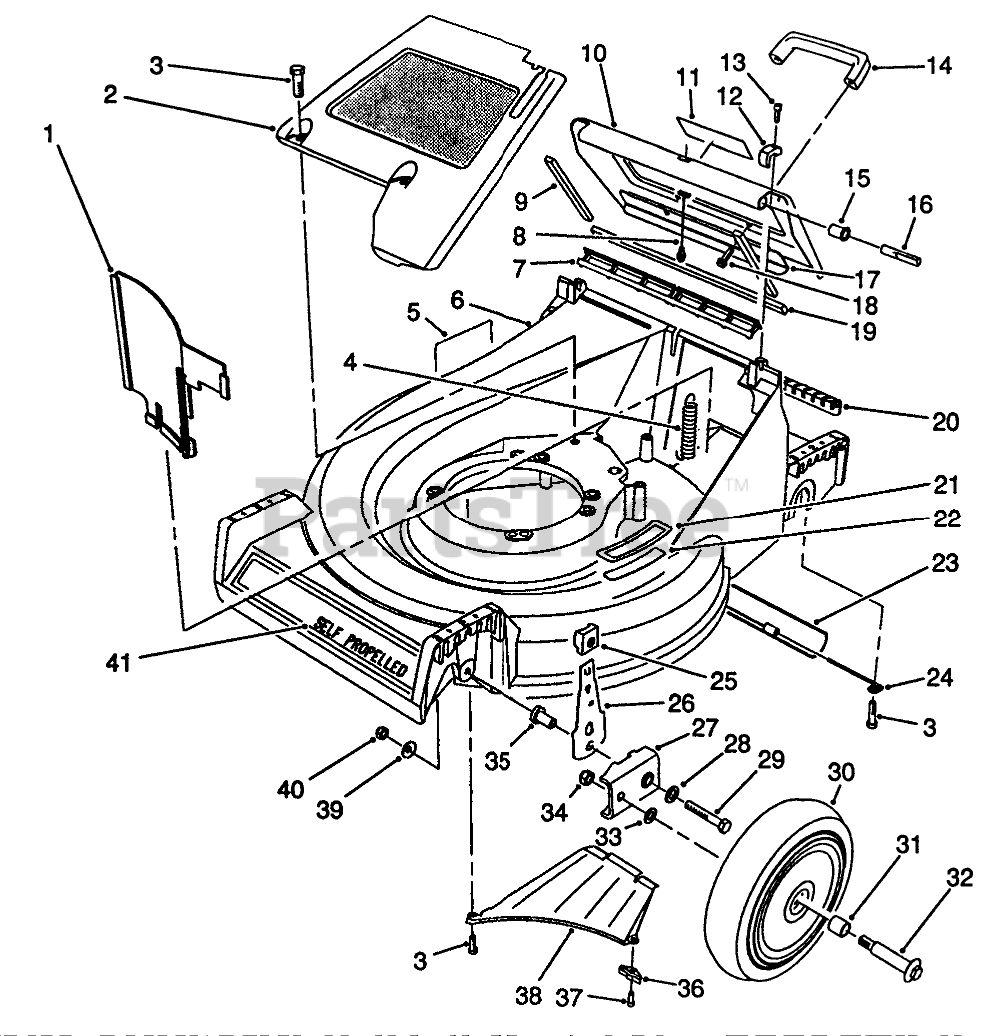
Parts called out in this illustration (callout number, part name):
1	PANEL-VERTICAL
2	PaneI-Screen
3	SCREW-HWHTF
4	EXTENSION-SPRING
5	DECAL-DANGER
6	21" Housing Assembly (Incl. Ref. #5, & 21-22)
7	DOOR SEAL
8	DOOR CABLE
9	DOOR SIDE SEAL
10	Door-Discharge (Incl. Ref. #9, 11, 17 & 19)
11	DECAL - WARNING
12	HINGE CLAMP
13	SCREW-HSH
14	HANDLE-DOOR
15	DOOR BUSHING
16	HINGE PIN
17	DOOR - BRACE
18	SCREW-HWH
19	DOOR END SEAL
20	ACCESS COVER
21	STEP PAD
22	STEP PAD DECAL
23	TRAILING SHIELD
24	LH SHIELD HANGER
25	KNOB-ARM
26	SPRING ARM ASSEMBLY
27	HP PIVOT ARM ASM
28	WASHER-FLAT
29	SCREW-HH
30	Wheel & Tire Assembly (Incl. Ref. #31)
31	BUSHING
32	WHEEL BOLT
33	WASHER
34	Nut
35	BUSHING-FLANGE
36	Bracket-Discharge
37	SCREW-HWHTF
38	Ramp Discharge
39	WASHER-BELLEVILLE
40	NUT-LOCK, NI
41	DECAL - 21 SP
